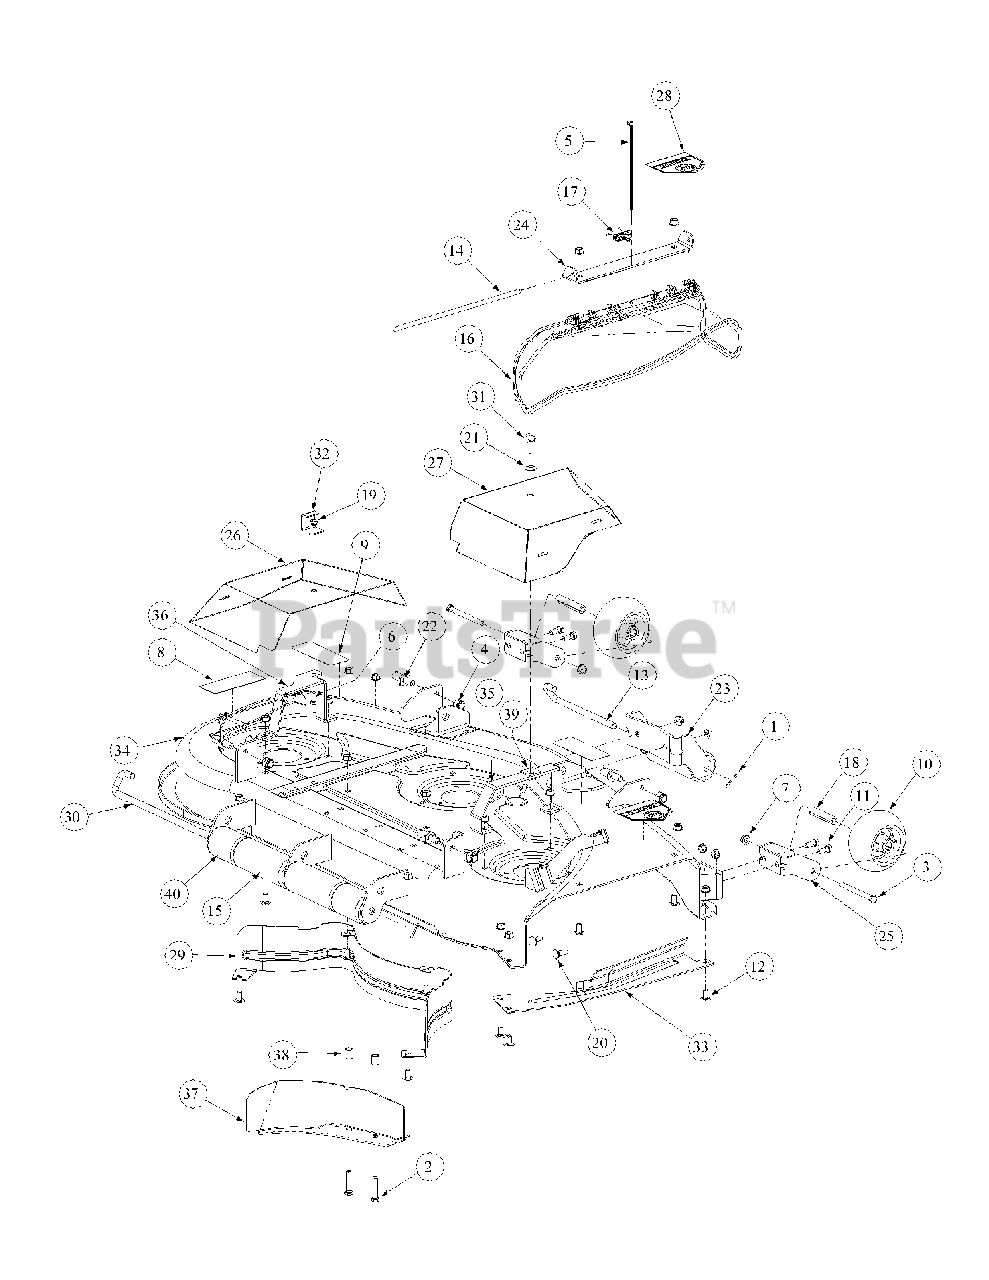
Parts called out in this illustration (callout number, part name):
1	Cotter Pin, .125 Dia x 1.0
2	Capscrew, 3/8-16 x 1-3/4
3	Hex Cap Screw, 3/8-16, 3.75
4	Lock Nut, Nylon Insert, 1/2-13
5	Cable Tie, 3/16 x .05 x 7.4
6	Hex Cap Screw, 5/16 -18 x 3/4
7	Hex Nut Flange Lock, 3/8-16
8	Decal, Rotating Blade
9	Decal, Warning Shield Missing
10	Wheel, 5.00 Dia
11	Hex Cap Screw, 3/8-16 x .88 Lg
12	Carriage Bolt, 3/8-16 x .75 Lg
13	Roller Pin, 1/2 Dia x 7.31 Lg
14	Hinge Pin, .375 x 14.06
15	Front and Rear Roller
16	Deflector Chute
17	Torsion Spring
18	Spacer Wheel
19	Hex Flange Lock Nut, 5/16-18
20	Carriage Bolt, 3/8-16 x 1
21	Belle Washer, .325 x .930 x .045
22	Pin, 5/8 Dia x 1.2 Lg
23	Front Roller Bracket
24	Chute Mounting Bracket
25	Castor Bracket
26	48" Left Hand Belt Cover
27	48" Right Hand Belt Cover
28	Decal, Danger Hands and Feet
29	48" Right Rear Inner Baffle
30	Roller Pin Rod
31	Thumb Screw, 5/16-18 x 1.0 Lg
32	Tension Rod Stop Bracket
33	Finger Guard
34	48" Stamped Deck
35	48" Right Hand Belt Cover Support Bracket
36	48" Left Hand Belt Cover Support Bracket
37	48" Deck Baffle
38	Spacer, .385 ID x .75 OD x .875
39	U-Nut, 5/16-18
40	Short Roller
